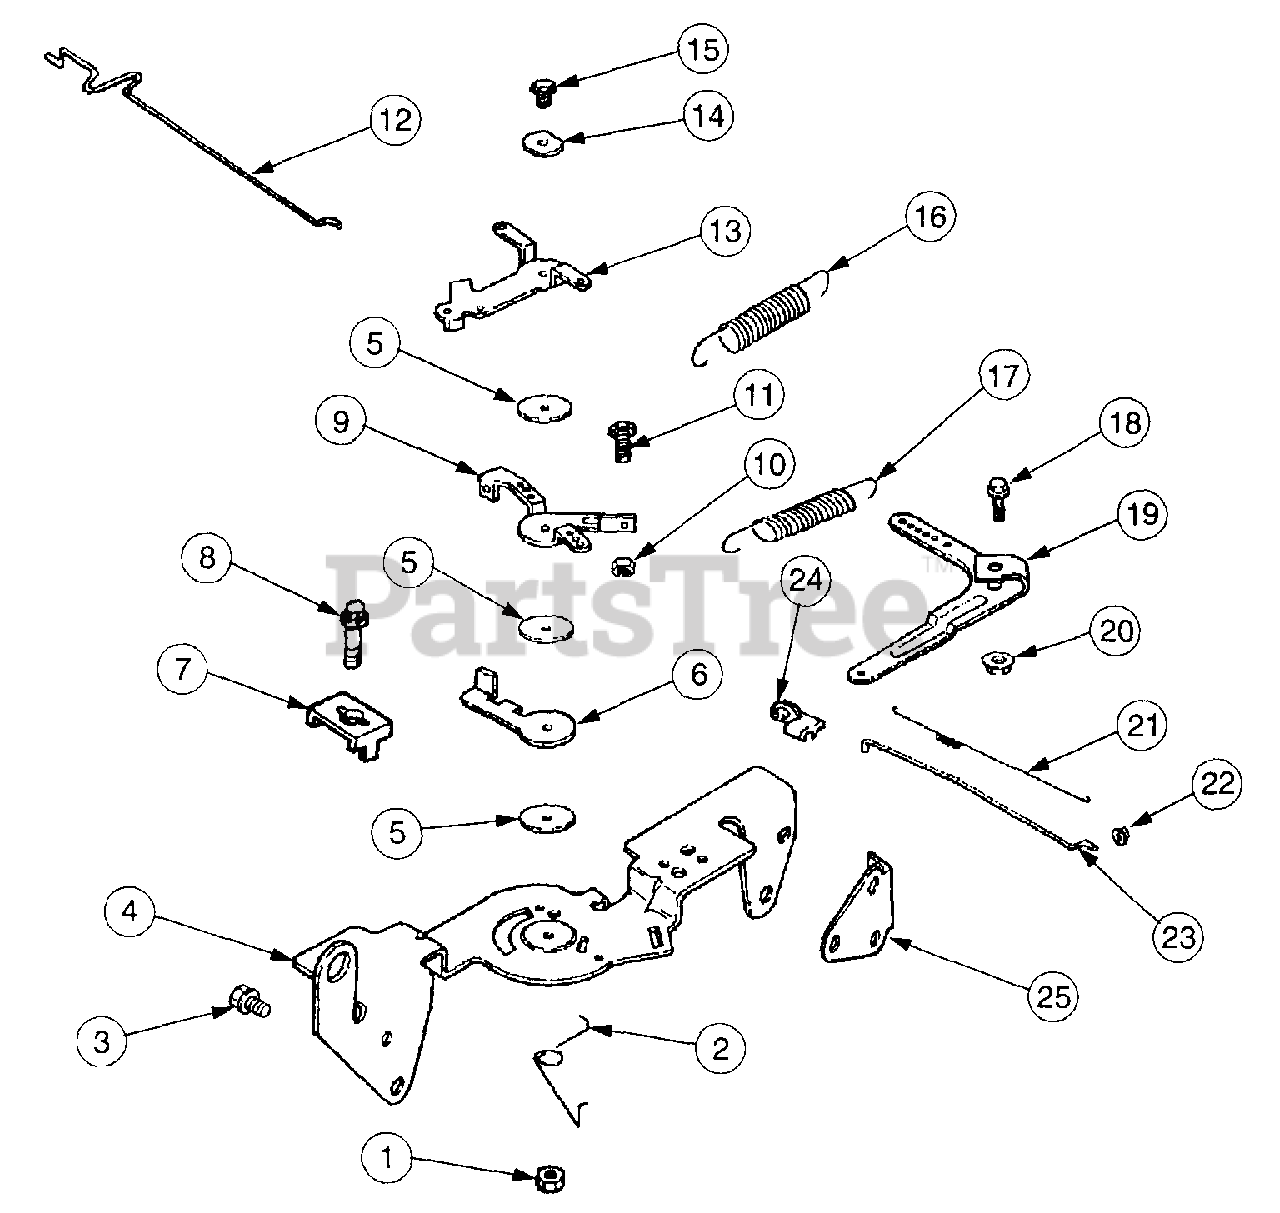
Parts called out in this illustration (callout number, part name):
1	Nut, Hex Lock M5 x 0.8
2	Spring, Choke Return
3	Screw, Hex Flange M6 x 1.0 x 16
4	Bracket, Control
5	Washer, Plain 5.5mm
6	Lever, Throttle Actuator
7	Clamp, Cable
8	Screw, Hex Flange M5 x 0.8 x 16
9	Lever, Throttle Control
10	Nut, Hex M4 x 0.7
11	Screw, Hex Cap M4 x 0.7 x 30
12	Linkage, Choke
13	Lever, Choke
14	Washer, Spring 1/4"
15	Screw, Hex Flange M5 x 0.8 x 20
16	Spring, Throttle Limiter
17	Spring, Governor
18	Screw, Hex Flange M6 x 1.0 x 25
19	Lever, Governor
20	Nut, Hex Flange M6 x 1.0
21	Spring, Linkage
22	Bushing, Linkage Retaining
23	Linkage, Throttle
24	Bushing, Linkage Retaining
25	Bracket, Support
